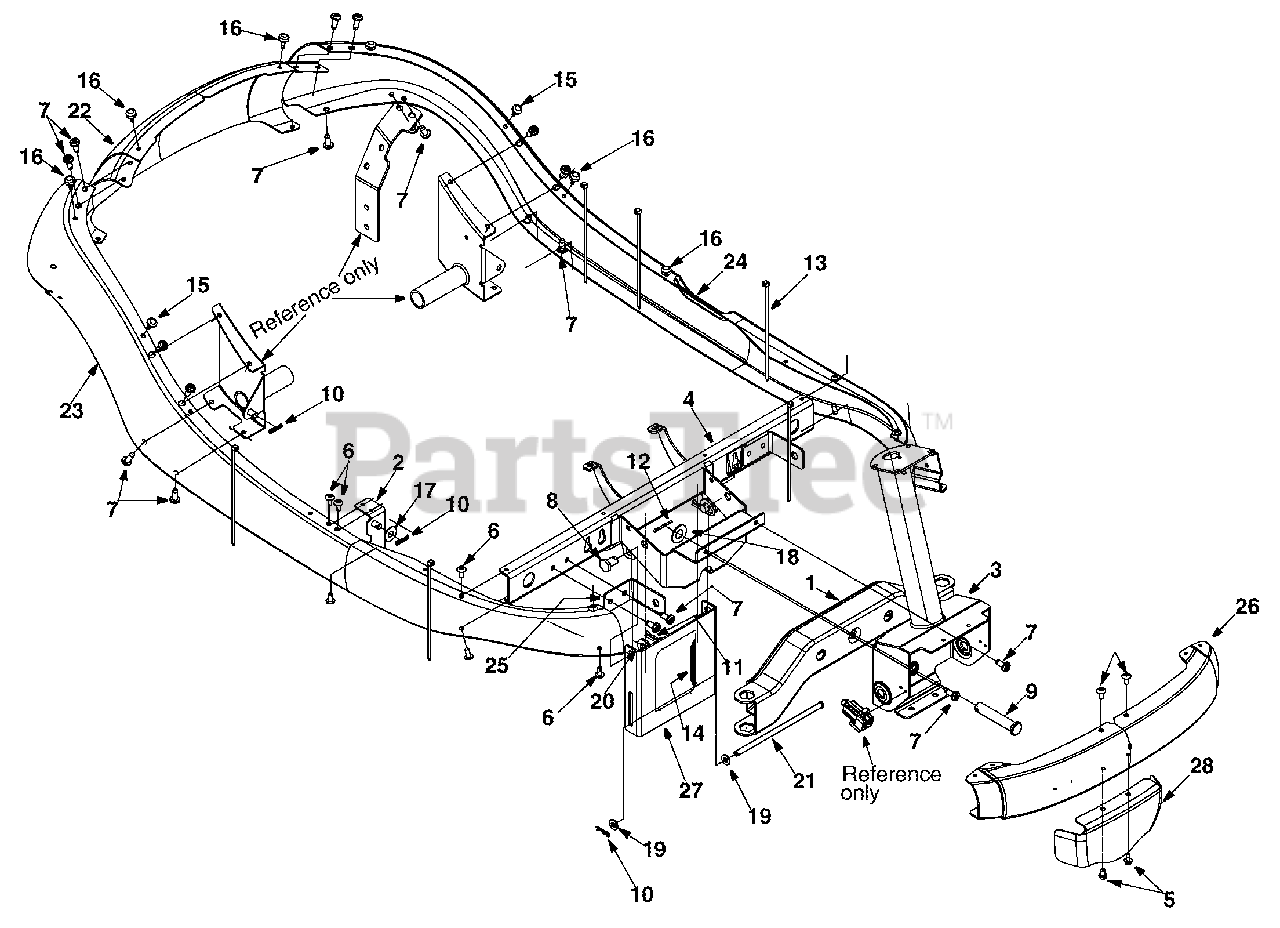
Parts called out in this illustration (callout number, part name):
5	TT screw 1/4-20 x 0.5"
6	AB Screw 1/4-14 x 0.625"
7	TT Screw 5/16-18 x 0.75"
8	Clevis Pin
9	Clevis Pin
10	Cotter Pin
11	Hairpin Clip
12	Cotter Pin
13	Cable Tie
14	Extension Spring
15	Rubber Bumper
16	Bumper
17	Flat Washer
18	Flat Washer
19	Flat Washer
20	Flat Washer
21	Deck Rod
